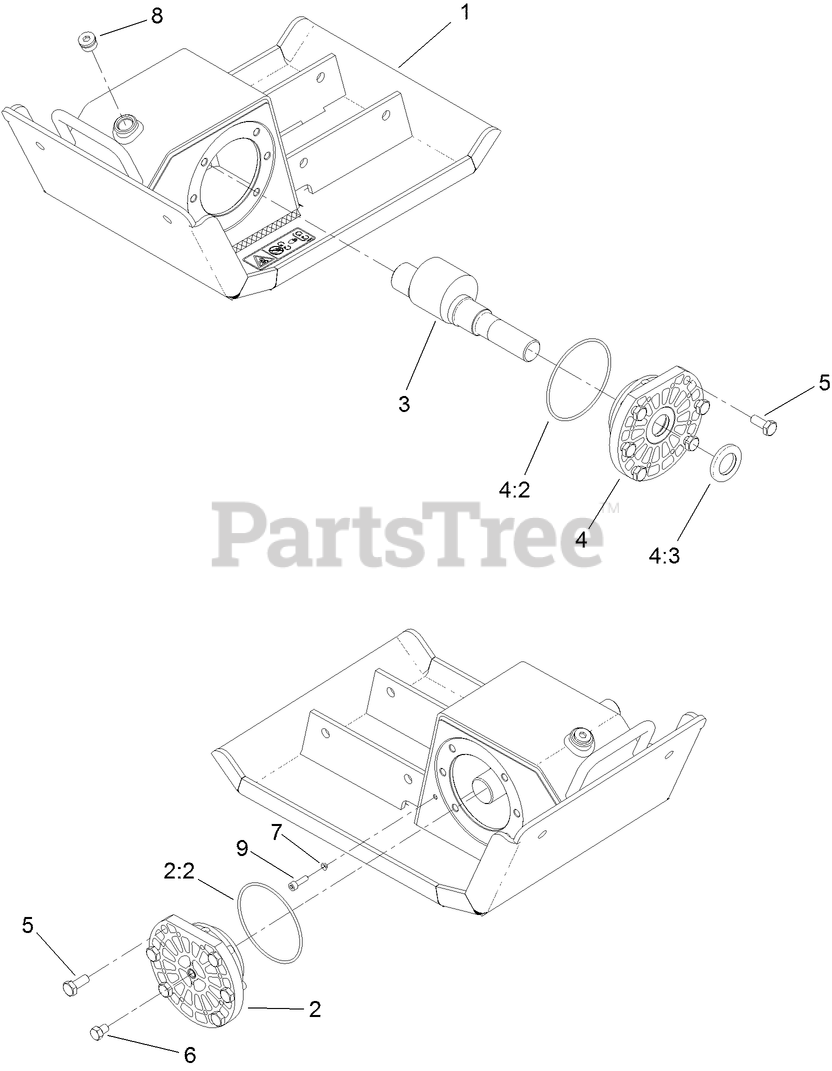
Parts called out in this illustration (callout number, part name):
1	BASE ASM
2	PLATE CAP BEARING ASM
2:2	O-RING
3	SHAFT-ECCENTRIC
4	PLATE CAP BEARING ASM
4:2	O-RING
4:3	SEAL-SHAFT
5	SCREW-HH
6	SCREW-HH
7	WASHER-SEALING, NYLTITE
8	FITTING-HYD
